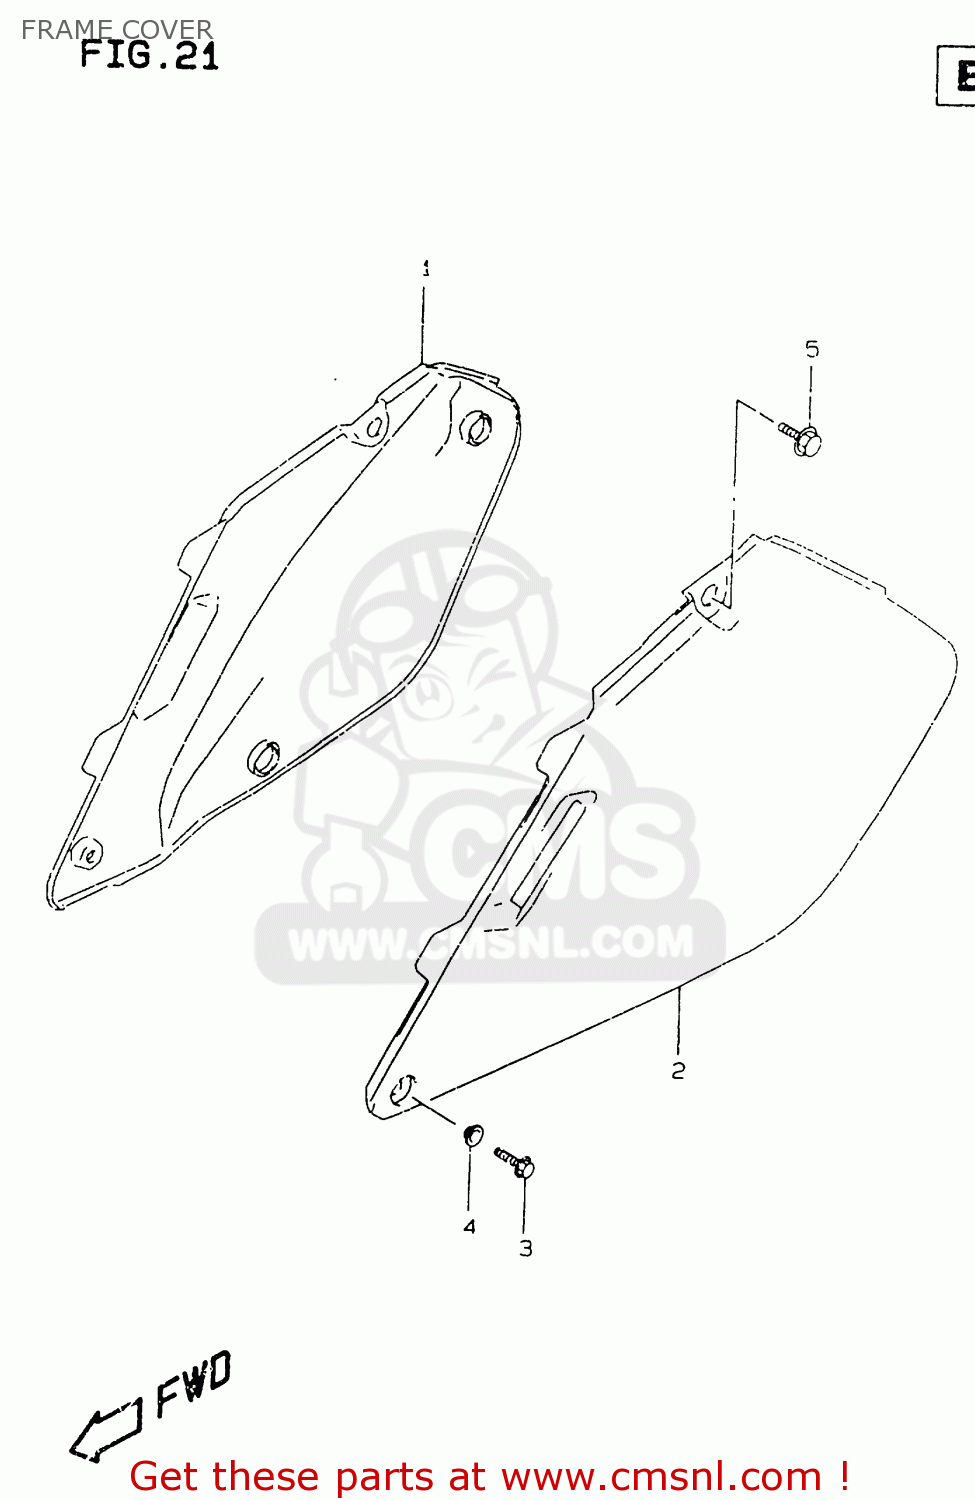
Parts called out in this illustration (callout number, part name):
1	COVER,FRAME,R(WHITE)
2	COVER,FRAME,LEFT
3	BOLT
4	WASHER
5	BOLT(6X16)
